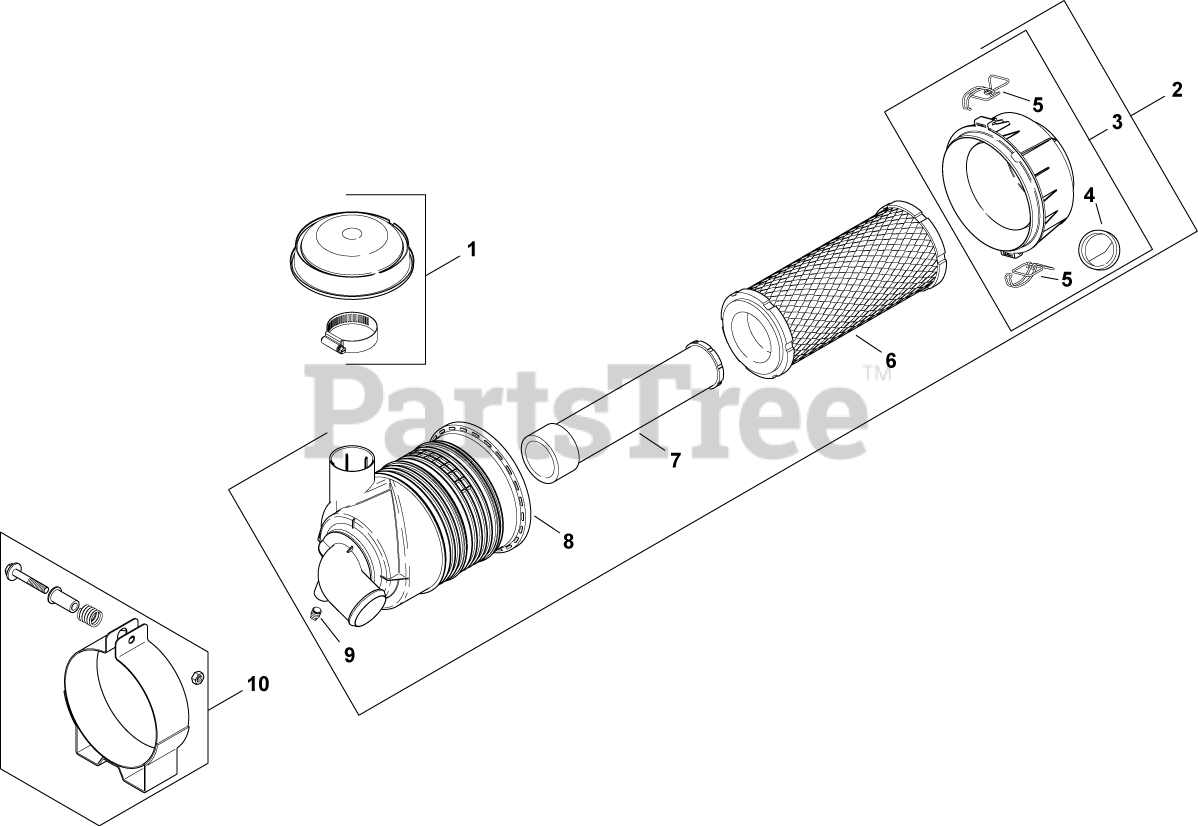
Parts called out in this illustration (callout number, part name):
1	HOOD, AIR CLEANER (5.25)-USE 25 324 04-S
2	AIR CLNR, CANISTER-USE 25 048 17-S
3	COVER ASSEMBLY, AIR CLEANER
4	VALVE, DUST EJECTOR
5	CLIP - USE 62 154 07-S
6	ELEMENT, AIR FILTER - PRIMARY
7	ELEMENT, AIR FILTER - SAFETY
8	HOUSING, HD AIR CLEANER
9	PLUG, PIPE
10	BRACKET, AIR CLEANER-USE 24 126 191-S
